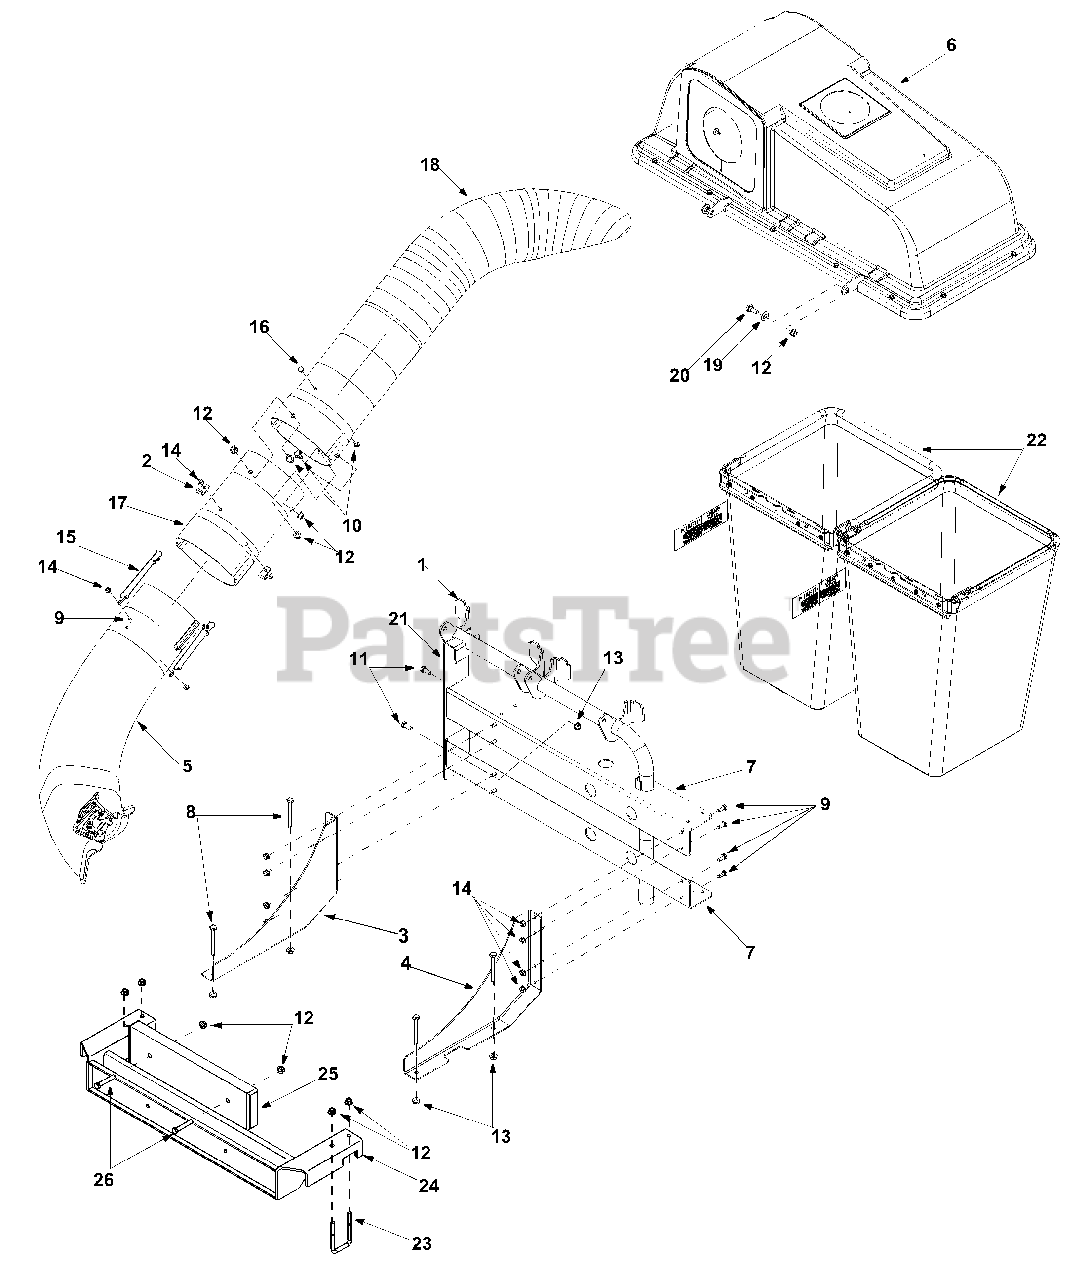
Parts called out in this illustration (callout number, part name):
2	Retainer Hook Bracket
5	Discharge Chute
6	Grass Catcher Cover
8	Hex Bolt 5/16-118 x 2.75"
9	Hex Bolt 1/4-20 x .620"
10	Washer Hd. Hex Bolt 3/8-16 x .625"
11	Hex Bolt 5/16-18 x .75"
12	Flange Lock Nut 3/8-16
13	Flange Lock Nut 5/16-18
14	Center Lock Flange Nut
15	Retainer Strap Assembly
17	Discharge Chute
18	Chute Tube
19	Beleville Washer
20	Shoulder Screw
22	Grass Bag
22	Screw, #10-24 x .5
22	Hex Sems Nut, 10-24
22	Bag
22	Self Tapping Screw, 5/16-18 x .625
23	U Bolt 3/8-16 x 1.50"
26	Hex Bolt 3/8-16 x 2.25"
